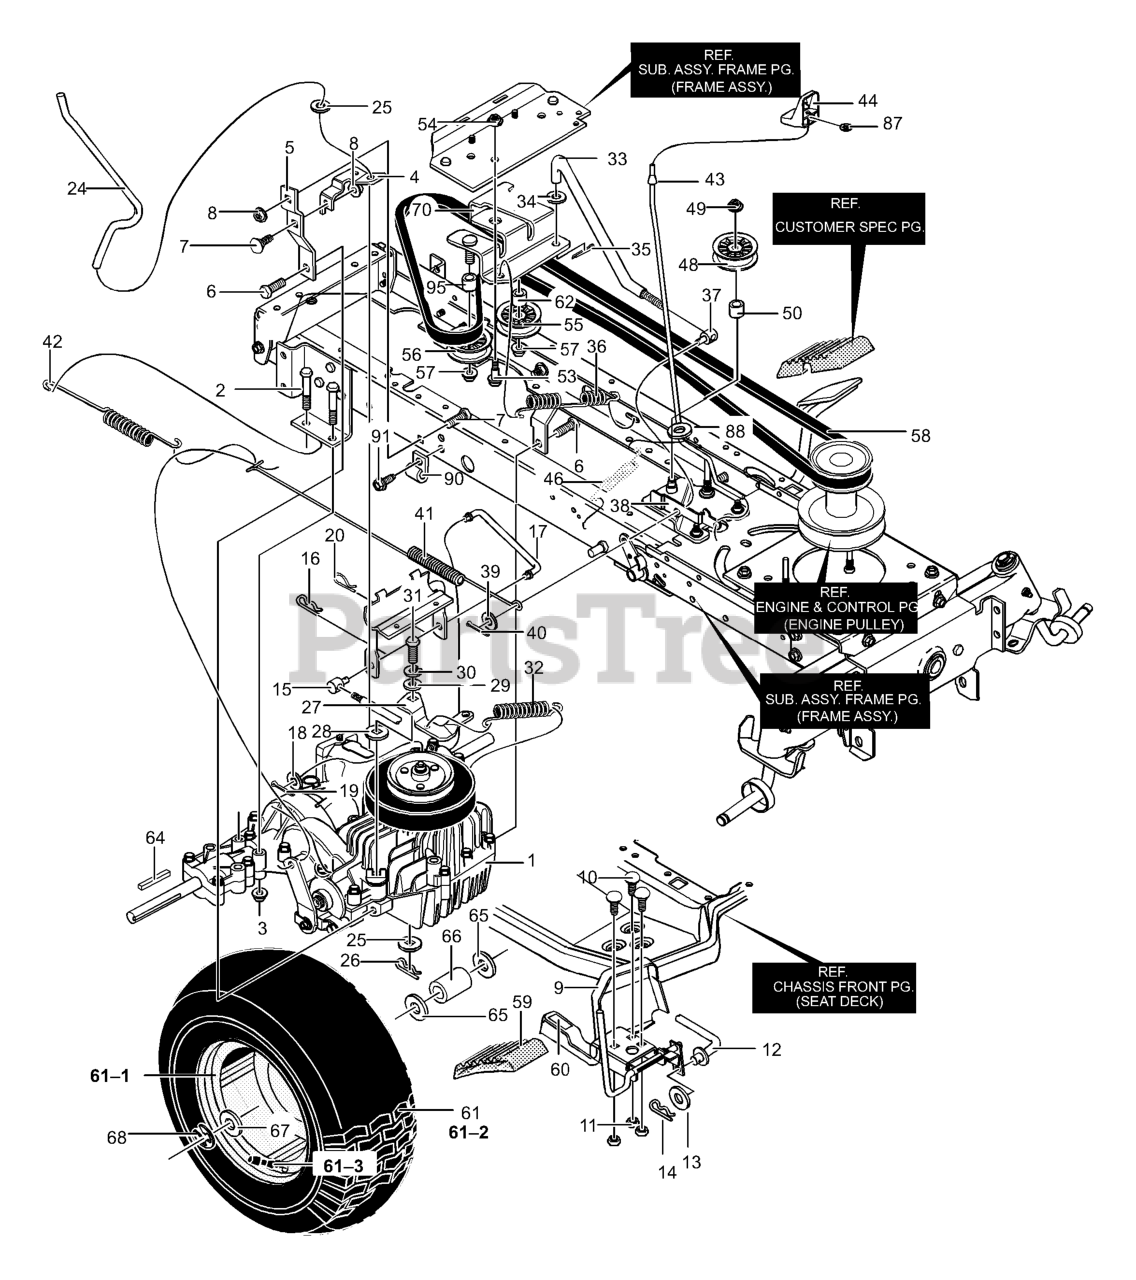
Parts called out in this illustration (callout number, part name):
1	Transaxle, Peerless **
2	Screw, 5/16-18 x 2.50
3	NUT, 5/16-18
4	BRACKET, DISCONNECT
5	TORQUE STRAP -RIGHT
6	Screw, 5/16-18 x 0.75
7	BOLT, CARRIAGE 5/16-18X .63
8	NUT, 5/16-18
9	WP, PEDAL ASSY HYDRO
10	BOLT, 5/16-18X .75
11	NUT, HEX 5/16-18
12	ROD, PEDAL LINK
13	WASHER
14	PIN, HAIR
15	ADJUST NUT 1/2-13
16	PIN, HAIR
17	ROD HYDRO LINK
18	WASHER, FLAT
19	PIN, COTTER
20	PIN, HAIR
24	ROD, DISCONNECT
25	WASHER, FLAT
26	PIN, COTTER
27	ARM, DISCONNECT
29	WASHER, FLAT
30	WASHER
31	SCREW, 1/4-28 X.75
32	SPRING, EXTENSION
33	ROD, CLUTCH
34	WASHER, FLAT
35	PIN, COTTER
36	SPRING, CLUTCH
37	NUT, ADJUSTING
38	LATCH, PARKING BRAKE
39	WASHER, FLAT
40	PIN, COTTER
41	SPRING, EXTENSION
42	SPRING, EXTENSION
43	ROD- PARKING BRAKE
44	PARKING BRAKE KNOB
46	SPRING - EXTENSION
48	PULLEY, IDLER
50	SPACER 1/2 TO 17MM
52	ASSEMBLY, BRACKET IDLER
54	NUT, 3/8-16
55	PULLEY, IDLER
56	PULLEY, IDLER
57	NUT, 3/8-16
58	BELT, MOTION DRIVE HYDRO
59	PAD, SPEED CONTROL
60	PAD, TOE SANDPAPER
61	TIRE & RIM 23X9.50-12
61-1	VALVE STEM
62	SPACER 1/2 TO 17MM
64	KEY, SQUARE
65	WASHER, FLAT
67	WASHER, FLAT
70	SPACER 1/2 TO 17MM
87	PUSHNUT
88	WASHER, FLAT
90	RETAINER WIRE
